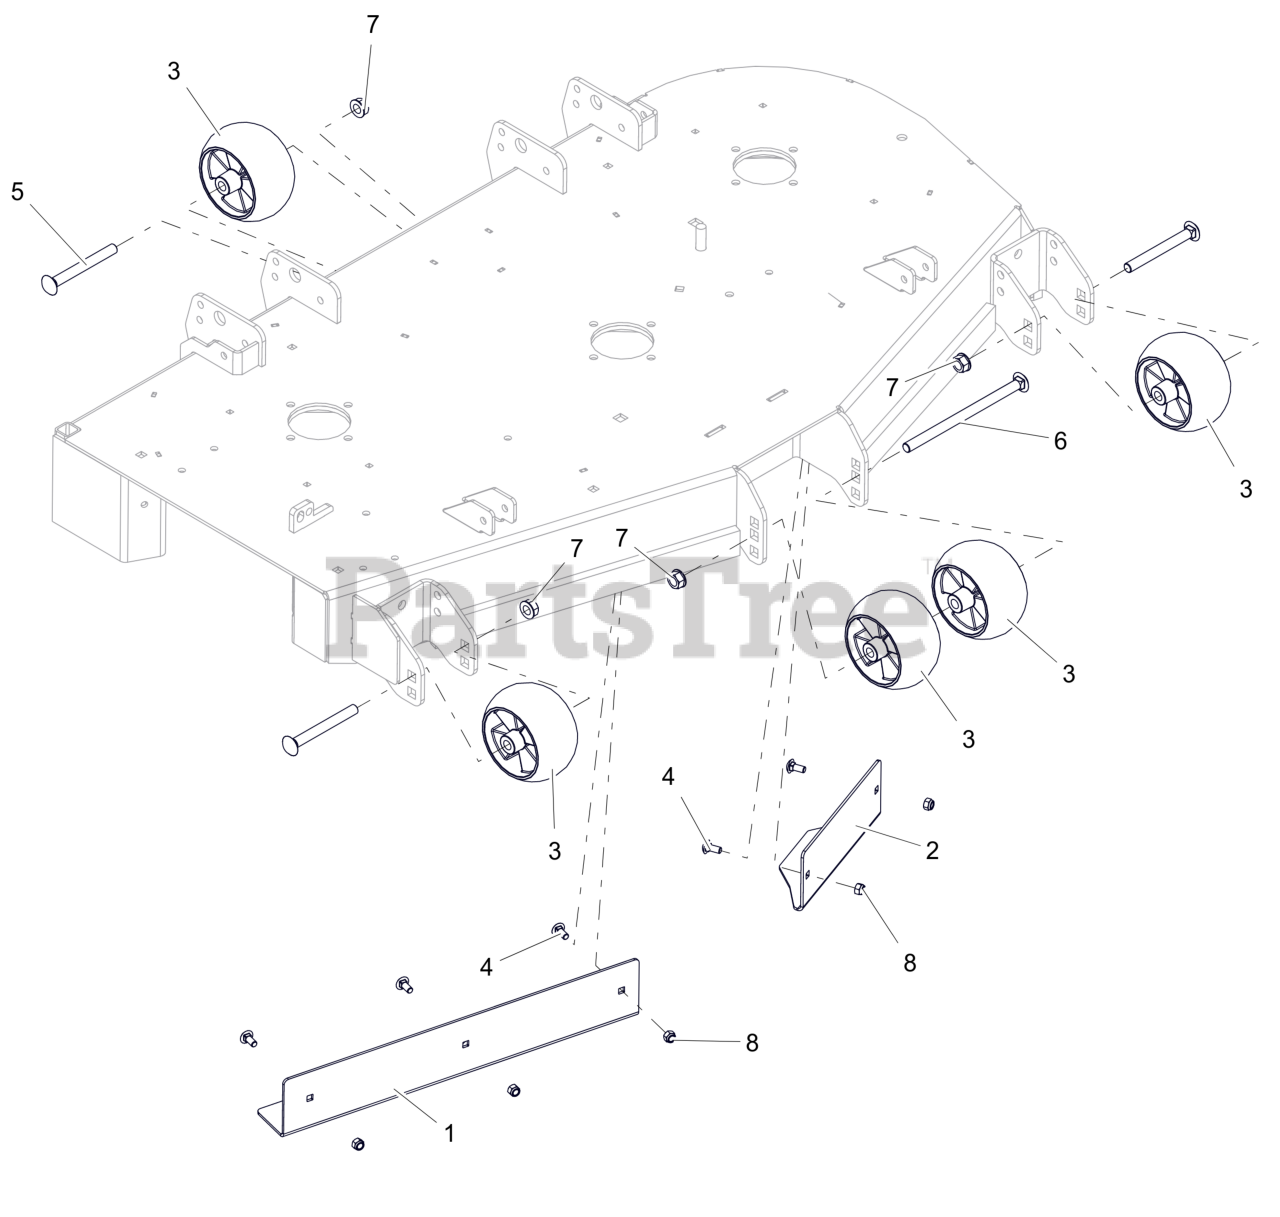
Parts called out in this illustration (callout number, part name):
1	BAFFLE, 48" RH VACUUM (RED)
2	BAFFLE, 44/48" LH VACUUM (RED)
3	WHEEL, ANTI SCALP - 5X3 CTR W/RIBS
4	BLT,RHSN .31-18X.75 G5 ZCC
5	BLT,RHNS .50-13X4.50 G5 ZCC NS
6	BLT,RHSN .50-13X8.00 G5 ZCC NS
7	NUT-LK-CTR-FLG .500-13 GG ZCC
8	NUT,NYL .31-18 G5 ZCC
